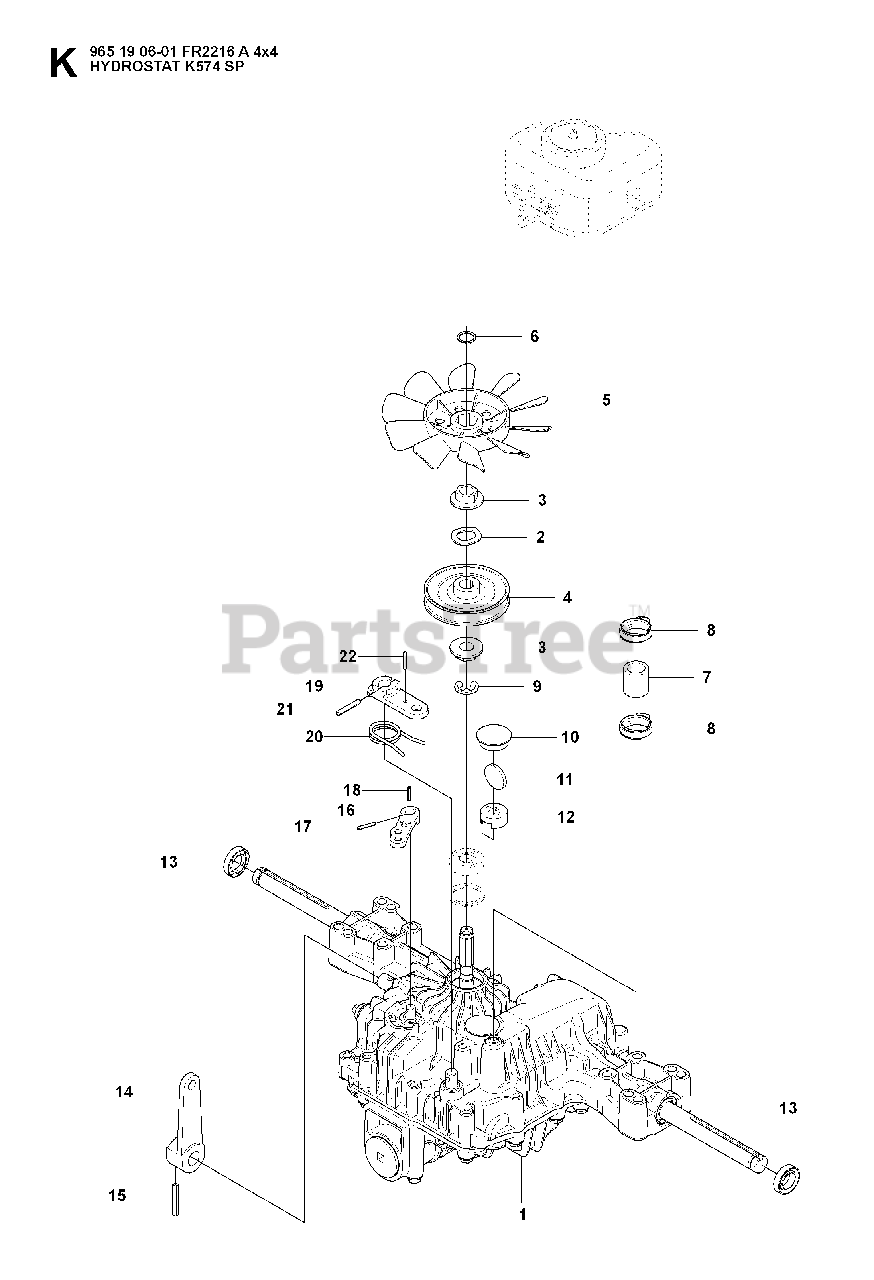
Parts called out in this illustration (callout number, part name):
1	HYDRAULMOTOR
2	WASHER **
5	FAN
6	RETAINING RING **
8	CLAMP
12	MAGNET HOLDER
13	SEALING
14	CONTROL LEVER
20	RETURN SPRING
